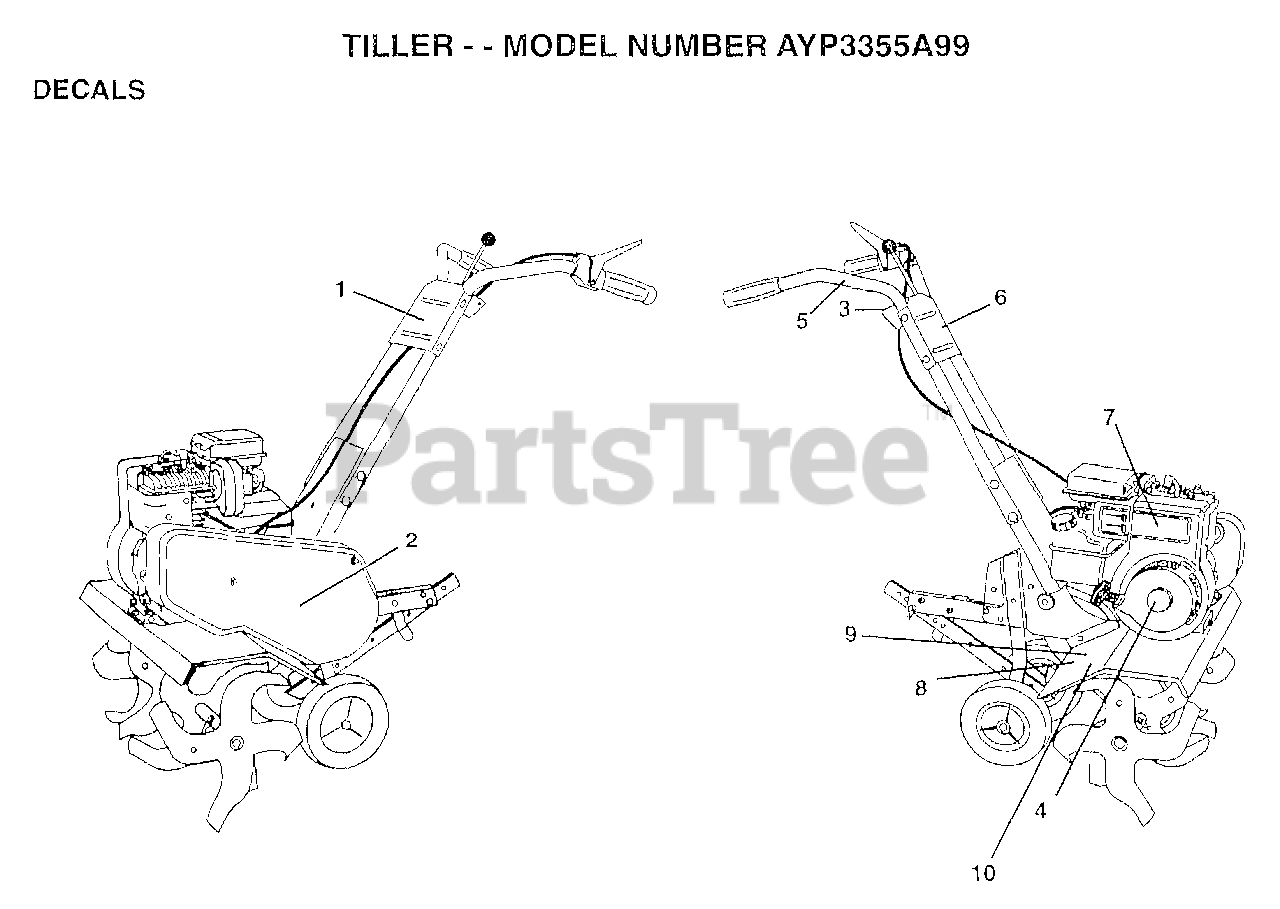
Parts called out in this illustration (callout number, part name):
1	DECAL.CNTRL.PNL.5
2	DECAL.BELT.GUARD
3	DECAL REVERSE
5	DECAL TI
6	DECAL-SERVICE REV. PANEL WIZARD
8	DECAL TI
10	DECAL.TINE.SHIELD
